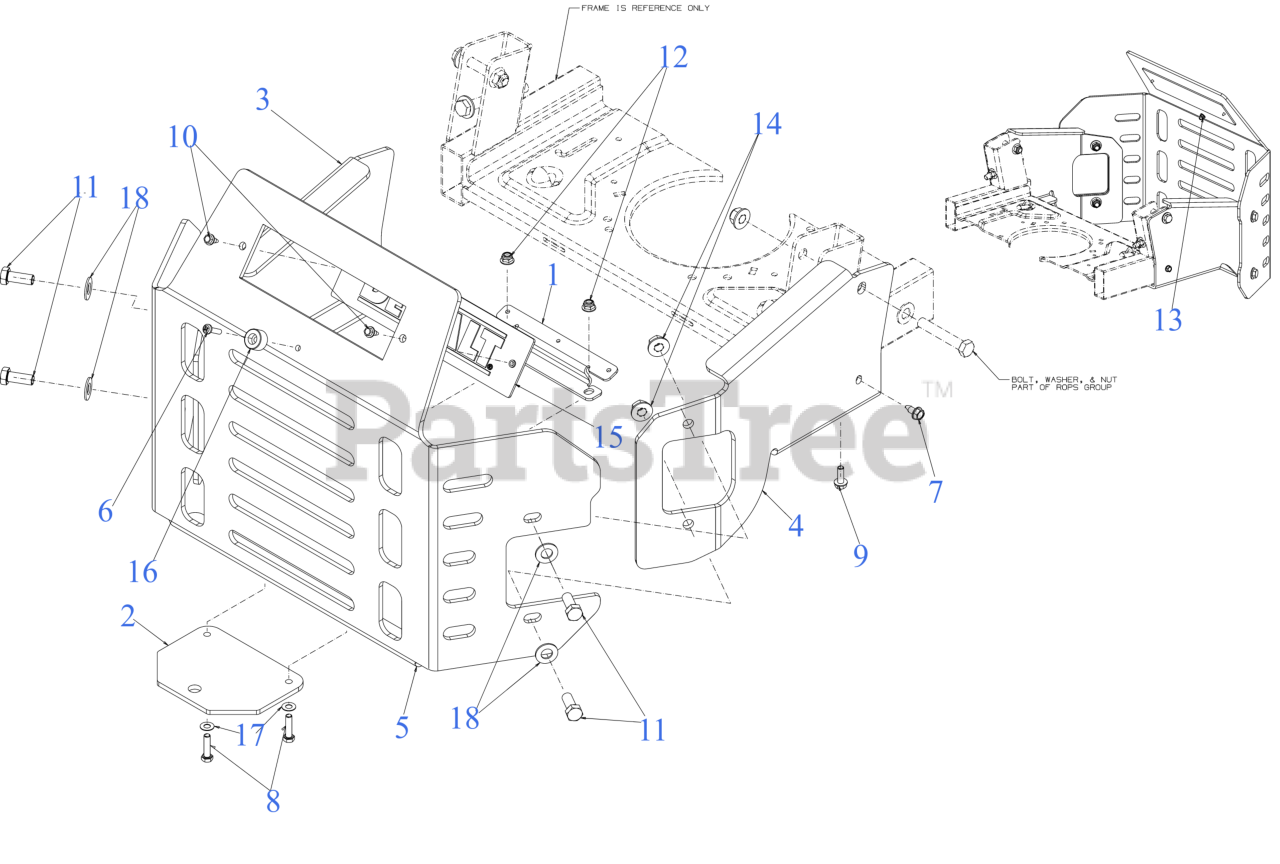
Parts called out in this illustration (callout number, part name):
1	MUFFLER BRACKET
2	HITCH PLATE
3	BUMPER BRACKET (LH)
4	BUMPER BRACKET (RH)
5	REAR BUMPER
6	MACHINE SCREW 1/4-20:1
7	SCREW 5/16-18 x .750
8	SCREW 5/16-18 x 1.25 GR5
9	SCREW 5/16-18 x .875 GR5
10	SCREW 1/4-20X.625
11	SCREW 1/2-13 x 1.25 GR5
12	FLANGE LOCK NUT 5/16-18
13	FLANGE LOCK NUT
15	DEWALT LOGO (DIE CAST)
16	BUMPER
17	FLAT WASHER
18	FLAT WASHER
